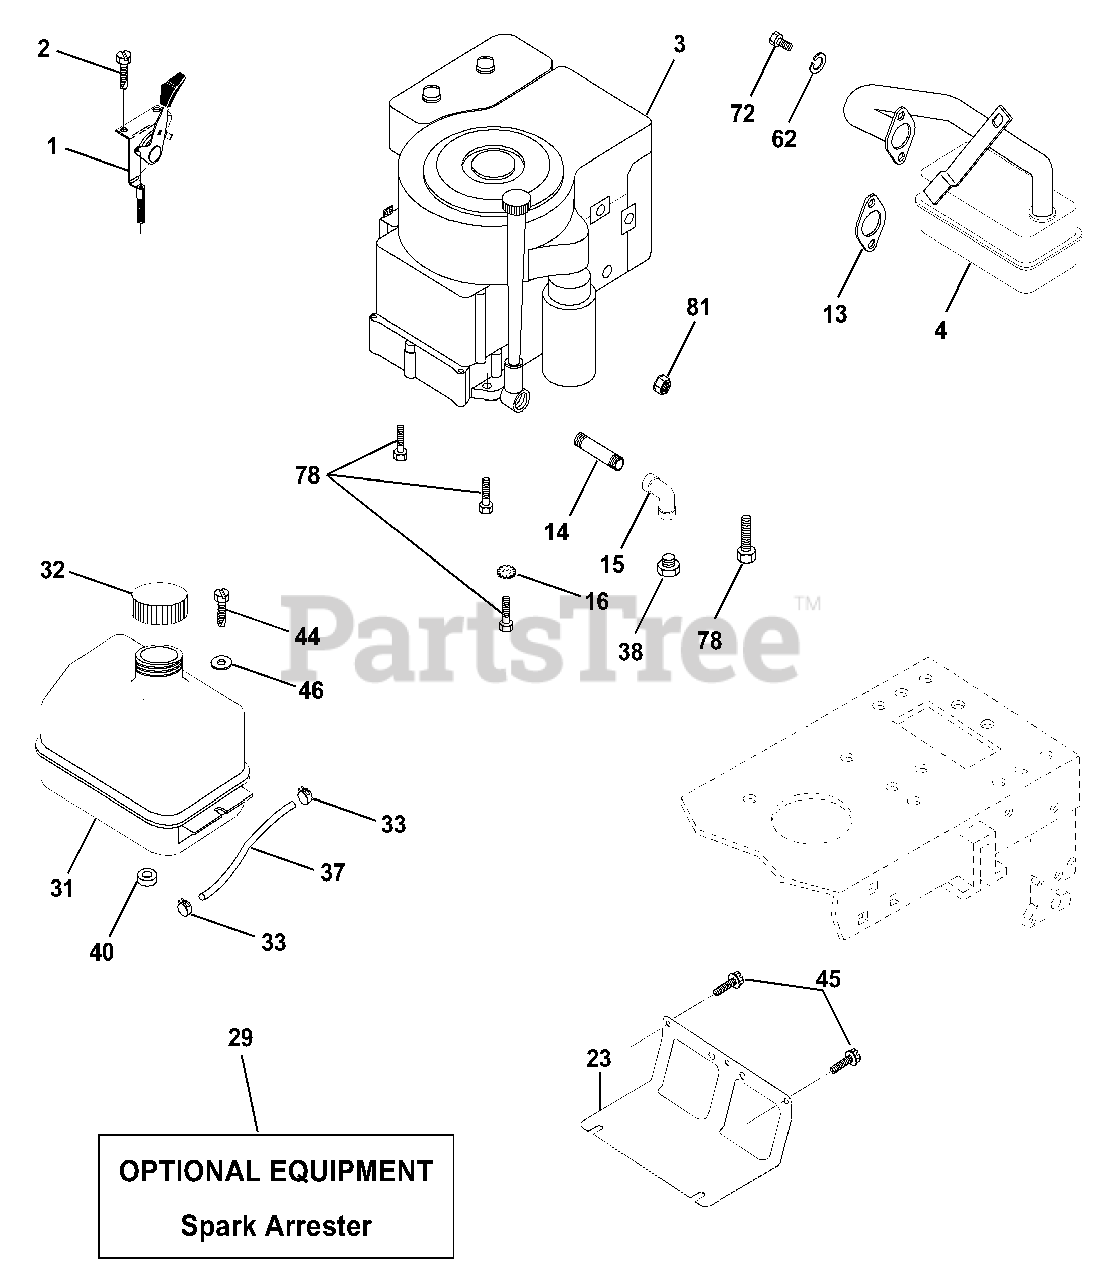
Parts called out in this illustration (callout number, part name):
1	Control Th/ch Flag
2	Screw Hex Thd Cut 1/4-20x5/8 T
4	Muffler Exhaust B&S Lc
13	Gasket Eng 1 313 Id Tin Plated
14	Nipple Pipe 3/8 Npt X 3"
15	Elbow Std 90 Degree 3/8-18 Npt
16	Washer Lock Ext Tooth 3/8
23	Shield BRN/DBR Guard
29	Kit Spark Arrestor (Flat Scrn)
31	Tank Fuel Front
32	Cap Asm Fuel
33	Clamp Hose
37	Line Fuel 20"
38	Oil Drain Plug
40	Bushing Snap Nyl Blk Fuel Line
44	Screw Thdrol 1/4-20 x 3/4
45	Screw Hex Wsh Thdrol 3/8-16
46	Washer 9/32 X 7/8 X 16 Ga
62	Washer Lock Hvy Hlcl Spr
72	Screw Hexcap 5/16-18 x 5/8
78	Screw 3/8-16 x 1-1/4
81	Nut Keps Hex 1/4-20 Unc
